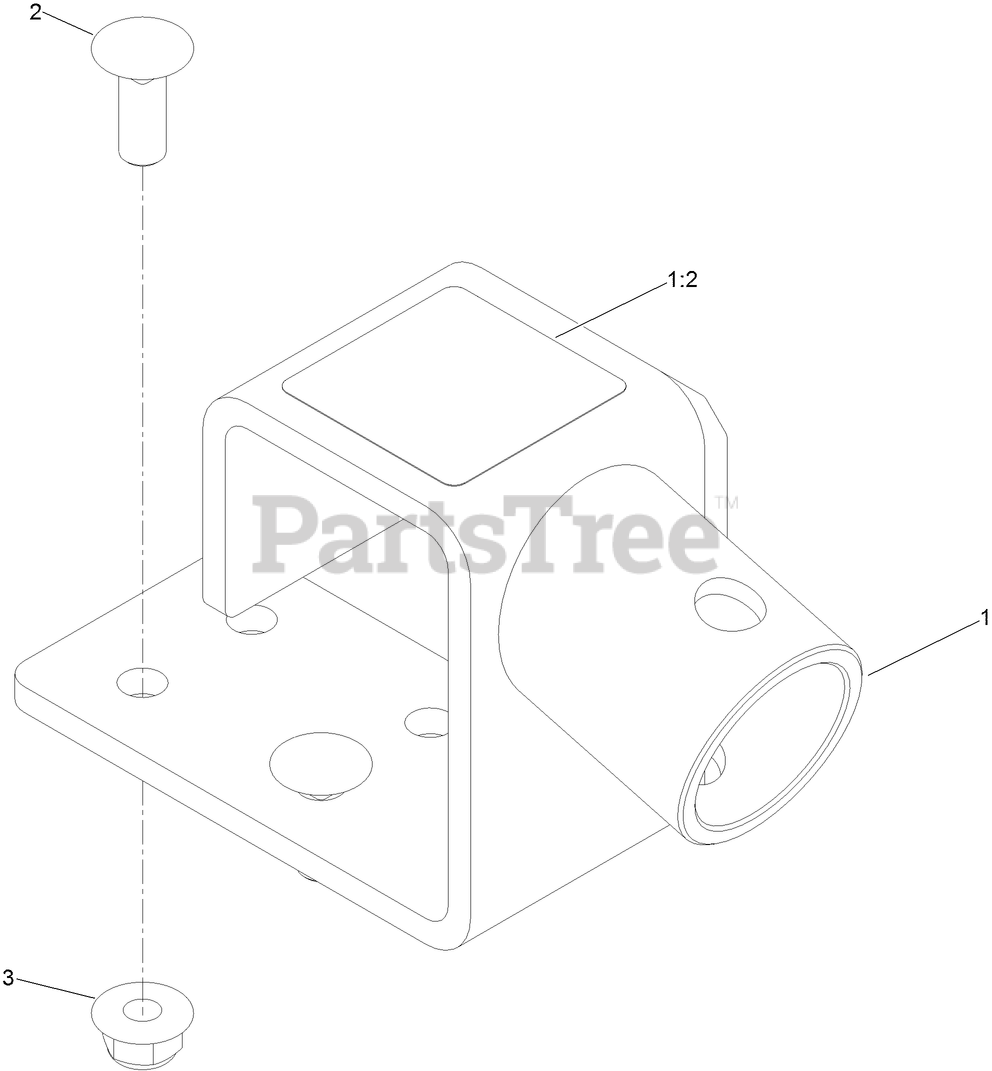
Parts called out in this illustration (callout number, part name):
1	MOUNT, JACK W/DECAL
1:2	DECAL-WARNING, JACK
2	SCREW-CARR
3	NUT-HF, NI
